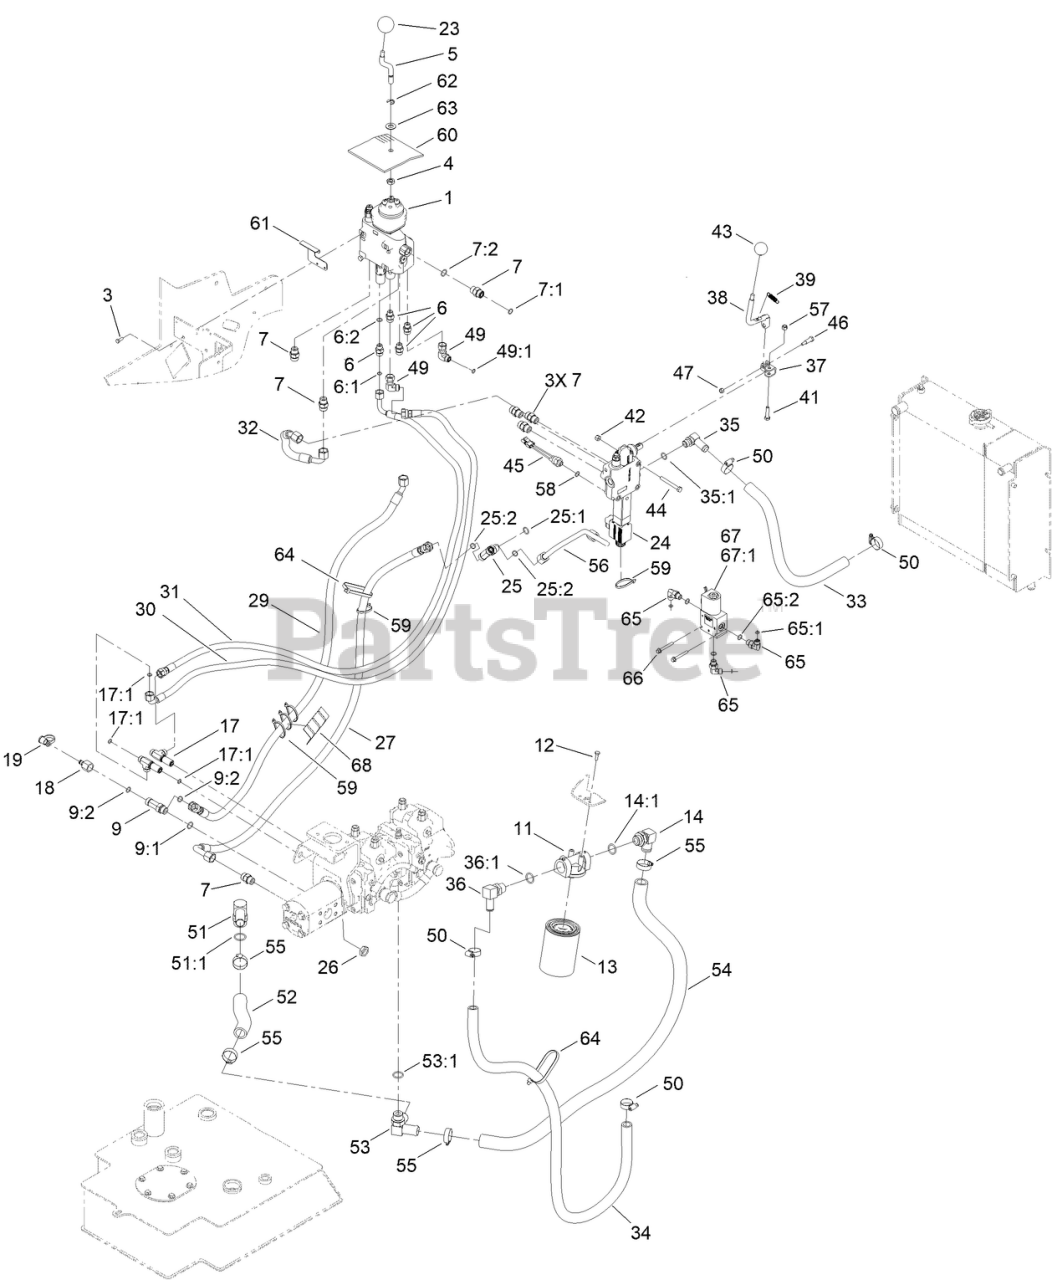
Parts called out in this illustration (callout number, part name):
1	VALVE-2 SPOOL
3	SCREW-HH
5	SHAFT-HANDLE, LIFT/TILT
6	FITTING-STRAIGHT
6:1	O-RING
6:2	O-RING
7	FITTING-STRAIGHT
7:1	O-RING
7:2	O-RING
9	FITTING-TEE
9:1	O-RING
9:2	O-RING
11	HEAD-FILTER
12	SCREW-HH
13	FILTER-OIL
14	FITTING-90
14:1	O-RING
17	FITTING-TEE, BULKHEAD
17:1	O-RING
18	FITTING
19	CAP-DUST
24	VALVE- AUX, DOUBLE DETENT
25	FITTING-HYD, TEE
25:1	O-RING
25:2	O-RING
26	NUT-LOCK
27	HYD HOSE ASM
29	HYD HOSE ASM
30	HYD HOSE ASM
31	HYD HOSE ASM
32	HYD HOSE
33	HOSE-RETURN
34	HOSE-RETURN
35	FITTING-ELBOW, 90
35:1	O-RING
36	FITTING-ELBOW, 90
36:1	O-RING
37	BRACKET-AUXILARY
38	HANDLE ASM
39	SPRING-EXTENSION
41	SCREW-HH
42	NUT-LOCK, NI
44	SCREW-HH
45	SWITCH-BALL
46	BOLT-SHOULDER
47	NUT-LOCK, NI
49	FITTING-HYD, 90 DEG
49:1	O-RING
50	CLAMP-HOSE
51	FITTING-HYD, 90 DEG
51:1	O-RING
52	HOSE-SUCTION
53	CONNECTOR
53:1	O-RING
54	HOSE-RETURN
55	CLAMP-HOSE
56	HYDRAULIC TUBE ASM
57	NUT-LOCK, NI
58	O-RING
59	TIE-CABLE
60	DEFLECTOR-AIR
61	BRACKET-DEFLECTOR
62	RING-RETAINING
63	WASHER-PIVOT
64	TIE-CABLE
65	FITTING-ELBOW, 90 DEG
65:1	O-RING
65:2	O-RING
66	SCREW-HHF
67	SOLENOID VALVE
67:1	SOLENOID COIL
68	PROTECTOR-HOSE
